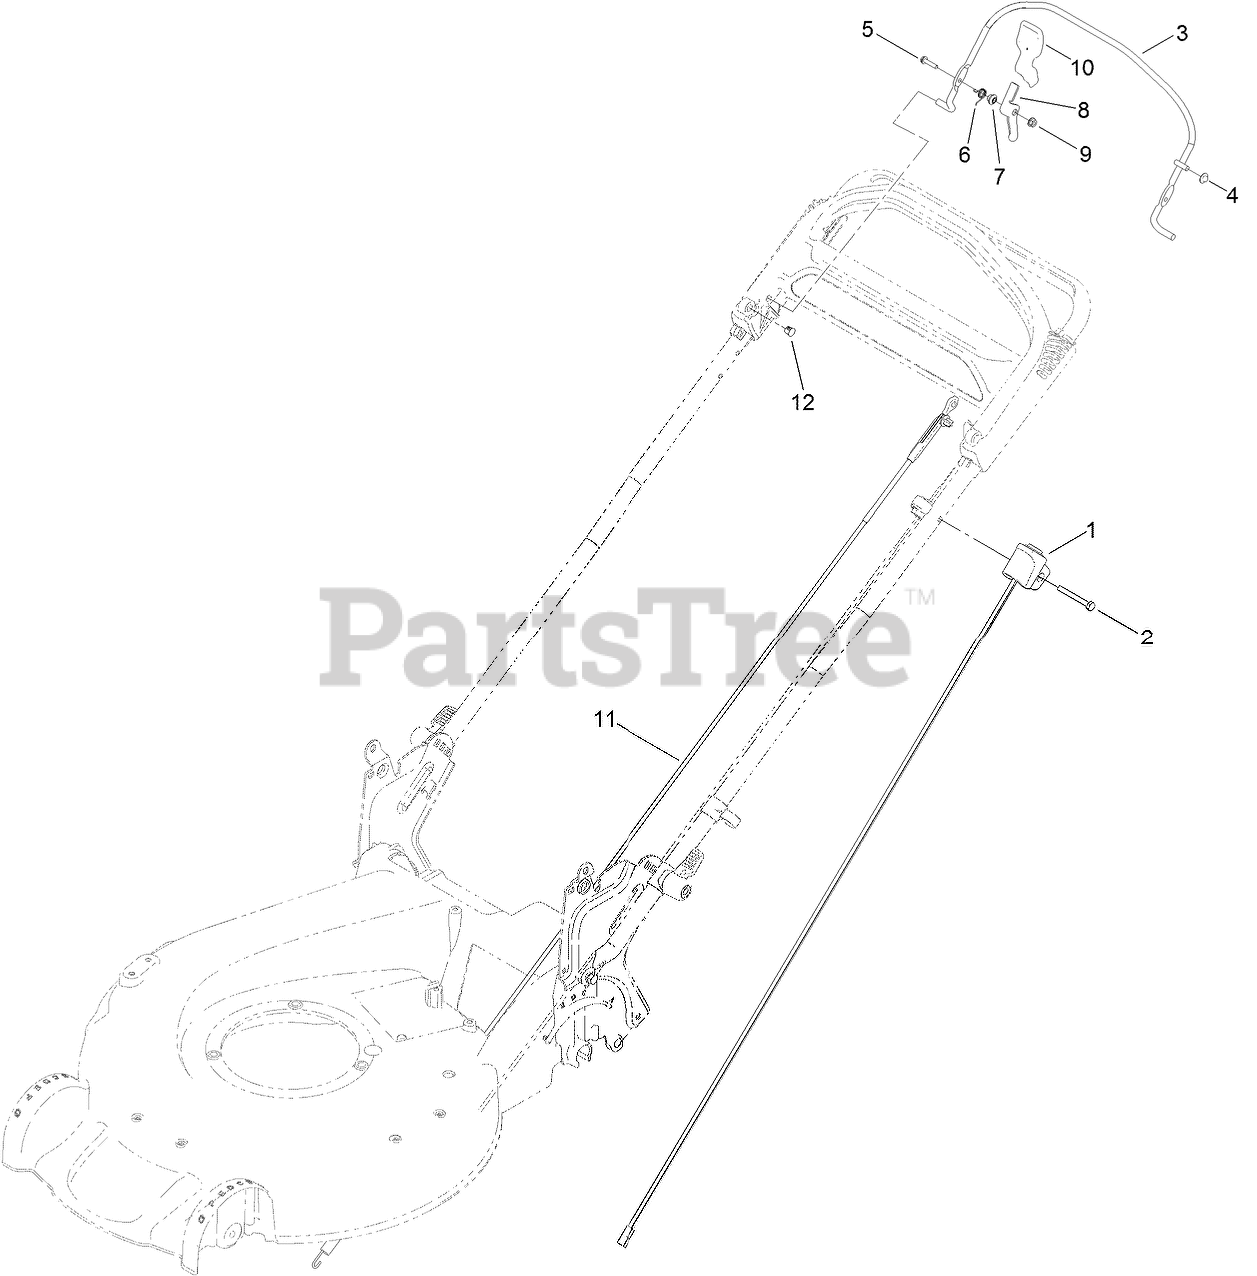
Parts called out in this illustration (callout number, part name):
1	HARNESS
2	SCREW-HH
3	BAIL-BRAKE
4	NUT-SPEED
5	SCREW-HWH
6	SPRING-TORSION
7	SPACER
8	LEVER
9	NUT-LOCK, FLANGE
11	CABLE ASM
12	Plug-Dome
